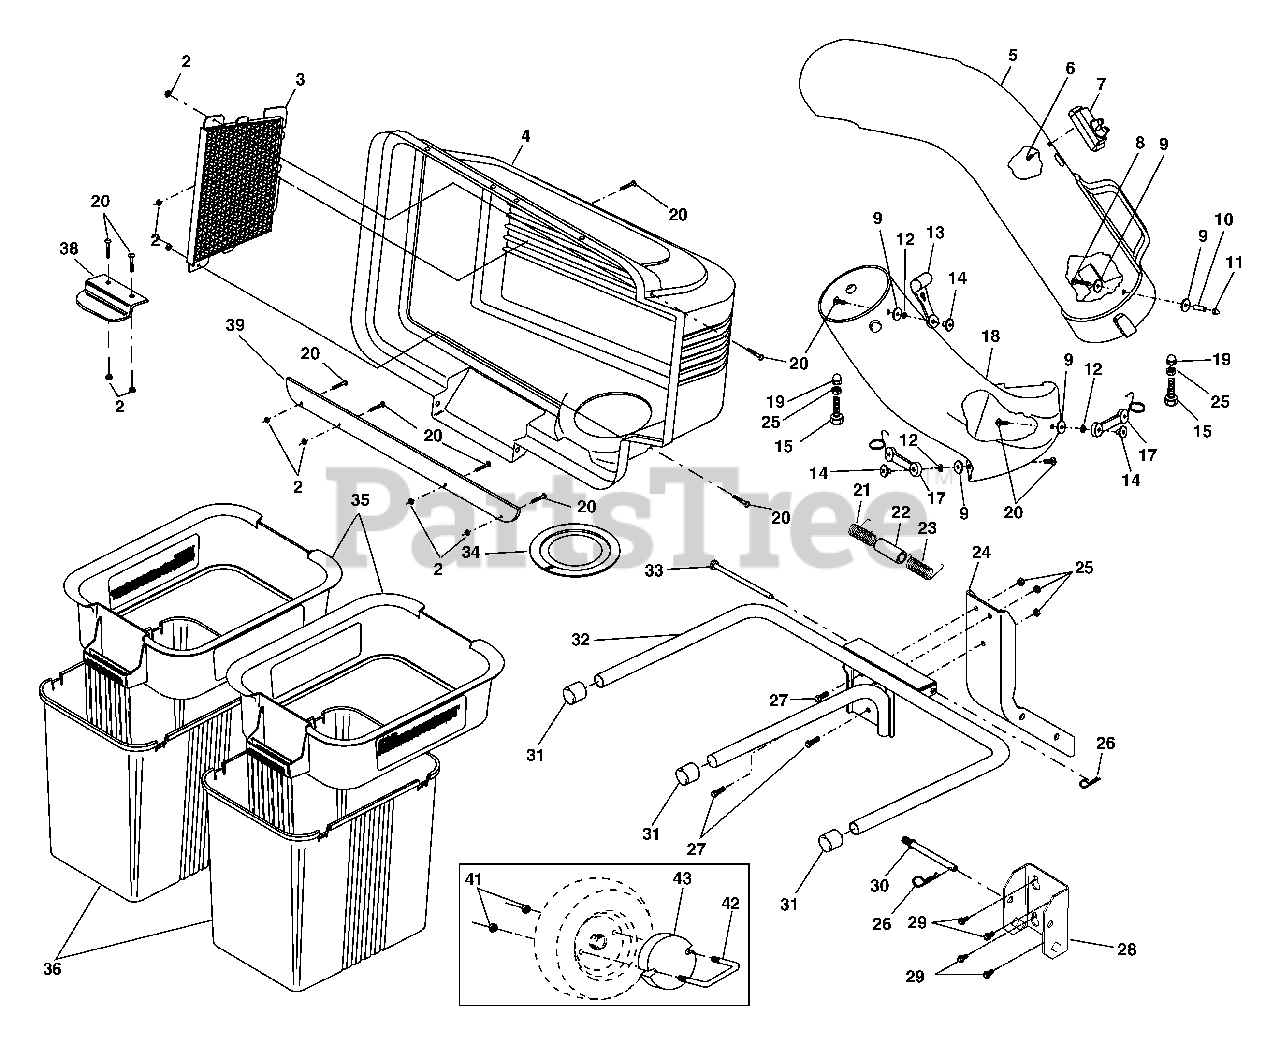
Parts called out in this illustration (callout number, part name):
2	Locknut #10-24
3	Screen, Cover
4	Cover Assembly
6	Screw, Special
7	Indicator, Dump Bag
8	Screw, #10-24 x 1-1/8
9	Washer 3/16 x 3/4
10	Spacer, Split
11	Nut, Acorn #10-24
14	Nut, Weld
15	Bolt, Hex 5/16-18 x 1
17	Latch Assy., Bagger
19	Nut, Acorn 5/16-18
20	Screw #10-24 x 5/8
21	Spring, Cover L.H. (black)
22	Spacer, Cover
23	Spring, Cover R.H. (gray)
24	Post, Support
25	Locknut 5/16 x 18
26	Spring, Retainer
27	Bolt, Carriage 5/16-18 x 3/4
28	Bracket, Mounting
29	Shoulder Bolt, Self-Tapping
30	Pin, Support Post
31	Cap, Tubing End
32	Bagger, Frame
33	Pin, Hinge
34	Gasket, Cover
35	Container, Top
36	Container, Bottom
38	Latch Handle, Cover
39	Strip, Reinforcement
41	Locknut 3/8-16
43	Weight, Wheel
